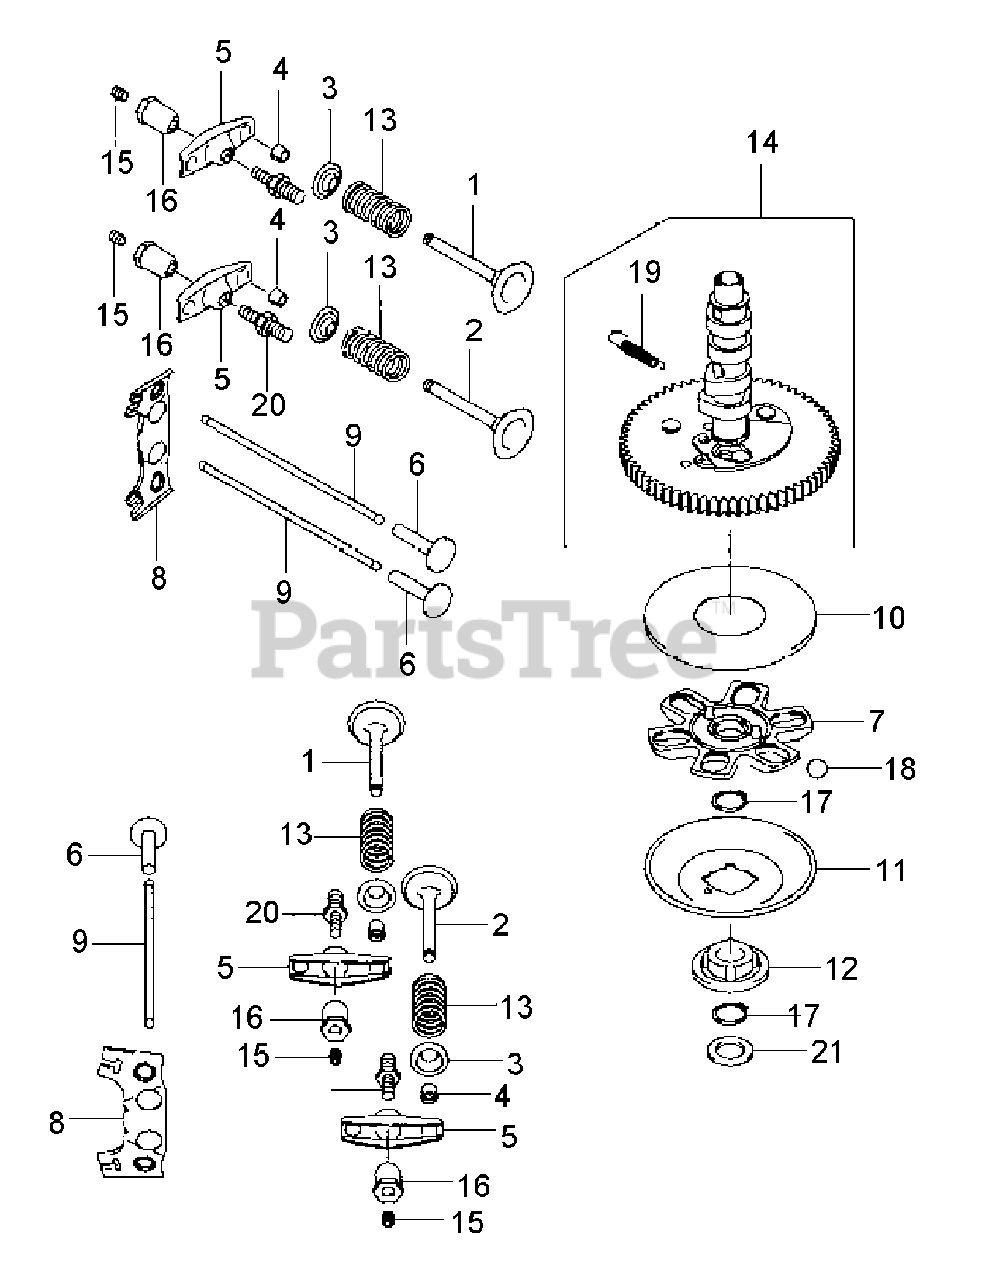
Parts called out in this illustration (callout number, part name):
2	VALVE-EXHAUST
3	RETAINER-VALVE SPRING
11	PLATE, GOVERNOR
13	SPRING-ENGINE VALVE
14	CAMSHAFT-COMP
17	RIING-SNAP
18	BALL
19	SPRING
